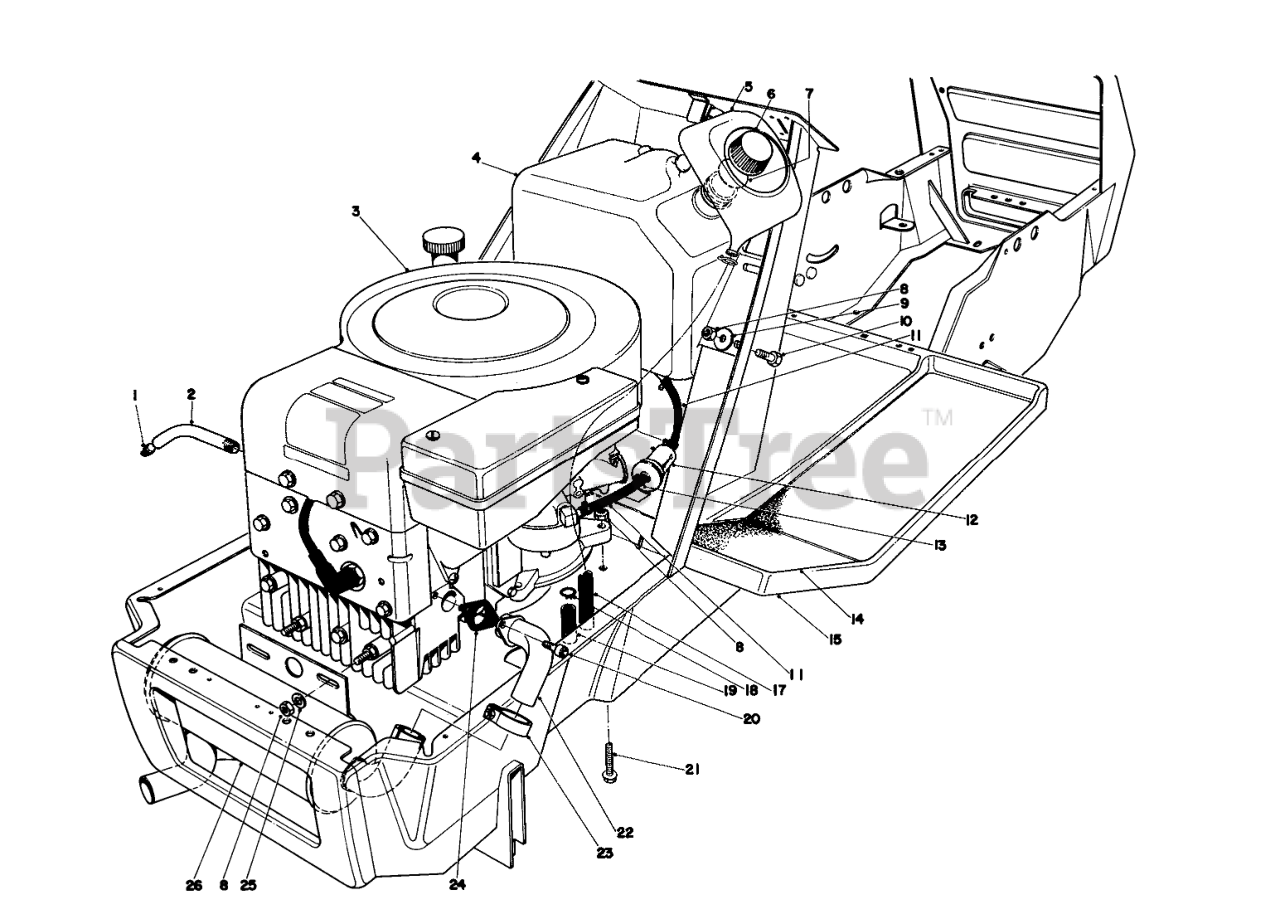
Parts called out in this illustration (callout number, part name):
1	PLUG-PIPE, SQH
2	OIL DRAIN TUBE
3	Engine
4	Gas Tank (Inch. Ref. #5)
5	Funnel-Overflow
6	Gas Cap (Inch. Ref. #7)
7	Gasket Gas Cap
8	NUT-LOCK, CONE
9	WASHER
10	SCREW-HH
11	GAS HOSE
12	FUEL FILTER
13	CLAMP-HOSE
14	LH FOOT TREAD
15	Frame
17	FUNNEL HOSE
18	HOSE CLAMP
19	CARB DRAIN HOSE
20	SCREW-HSH
21	SCREW-HH
22	Exhaust Pipe
23	MUFFLER CLAMP
24	Exhaust Gasket
25	WASHER-PLAIN
26	MUFFLER
